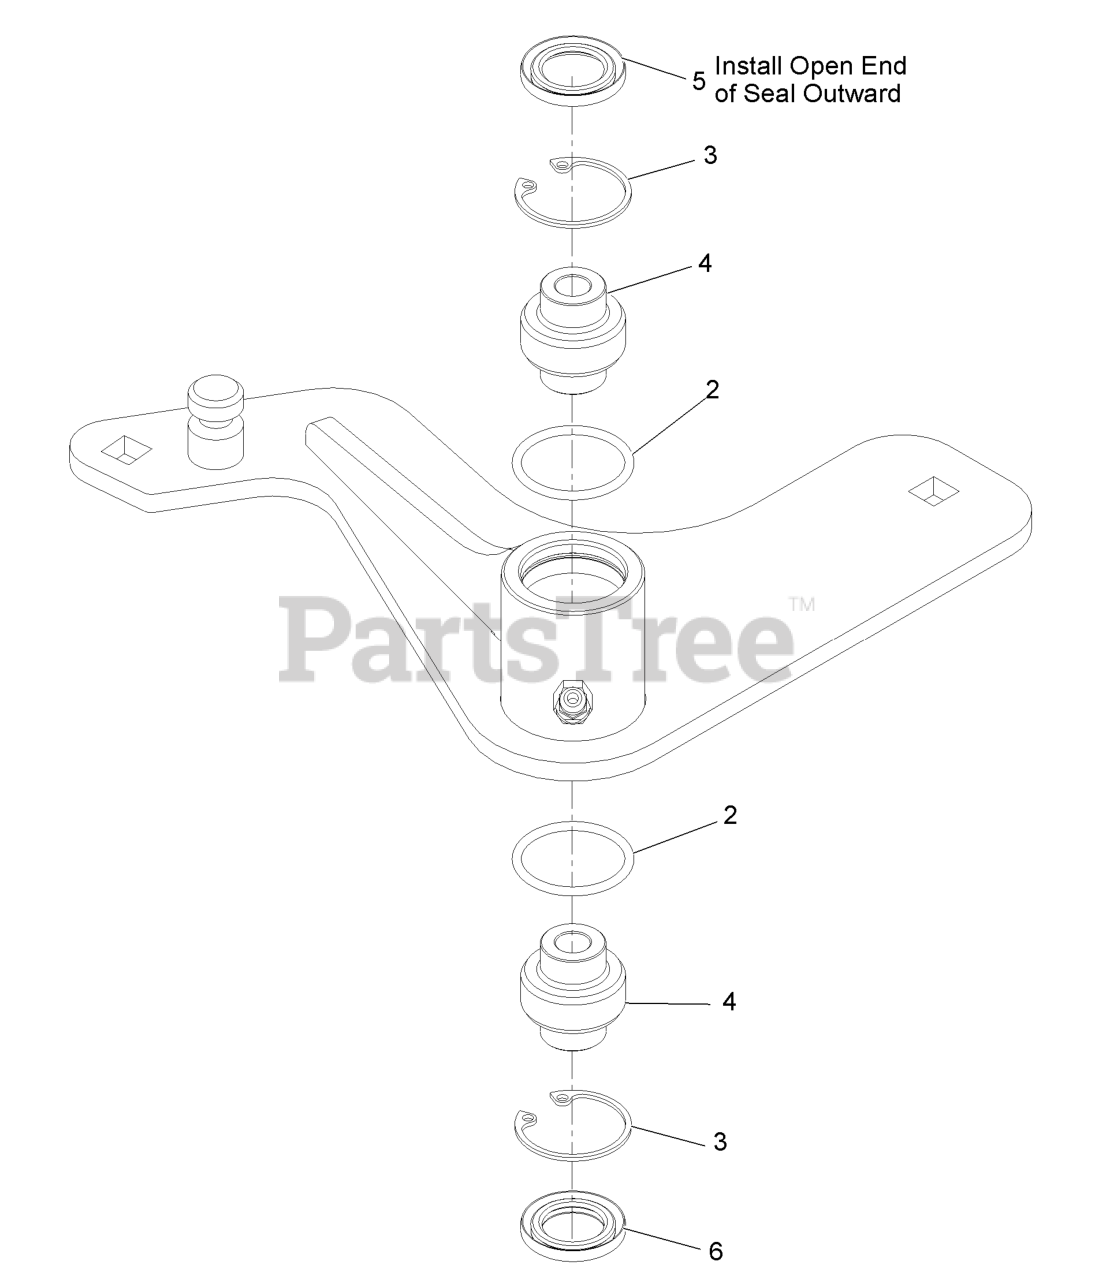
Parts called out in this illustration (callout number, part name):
3	RING-SNAP
4	BEARING-SPHERICAL
5	SEAL-LIP, SINGLE
6	SEAL-LIP, DOUBLE
